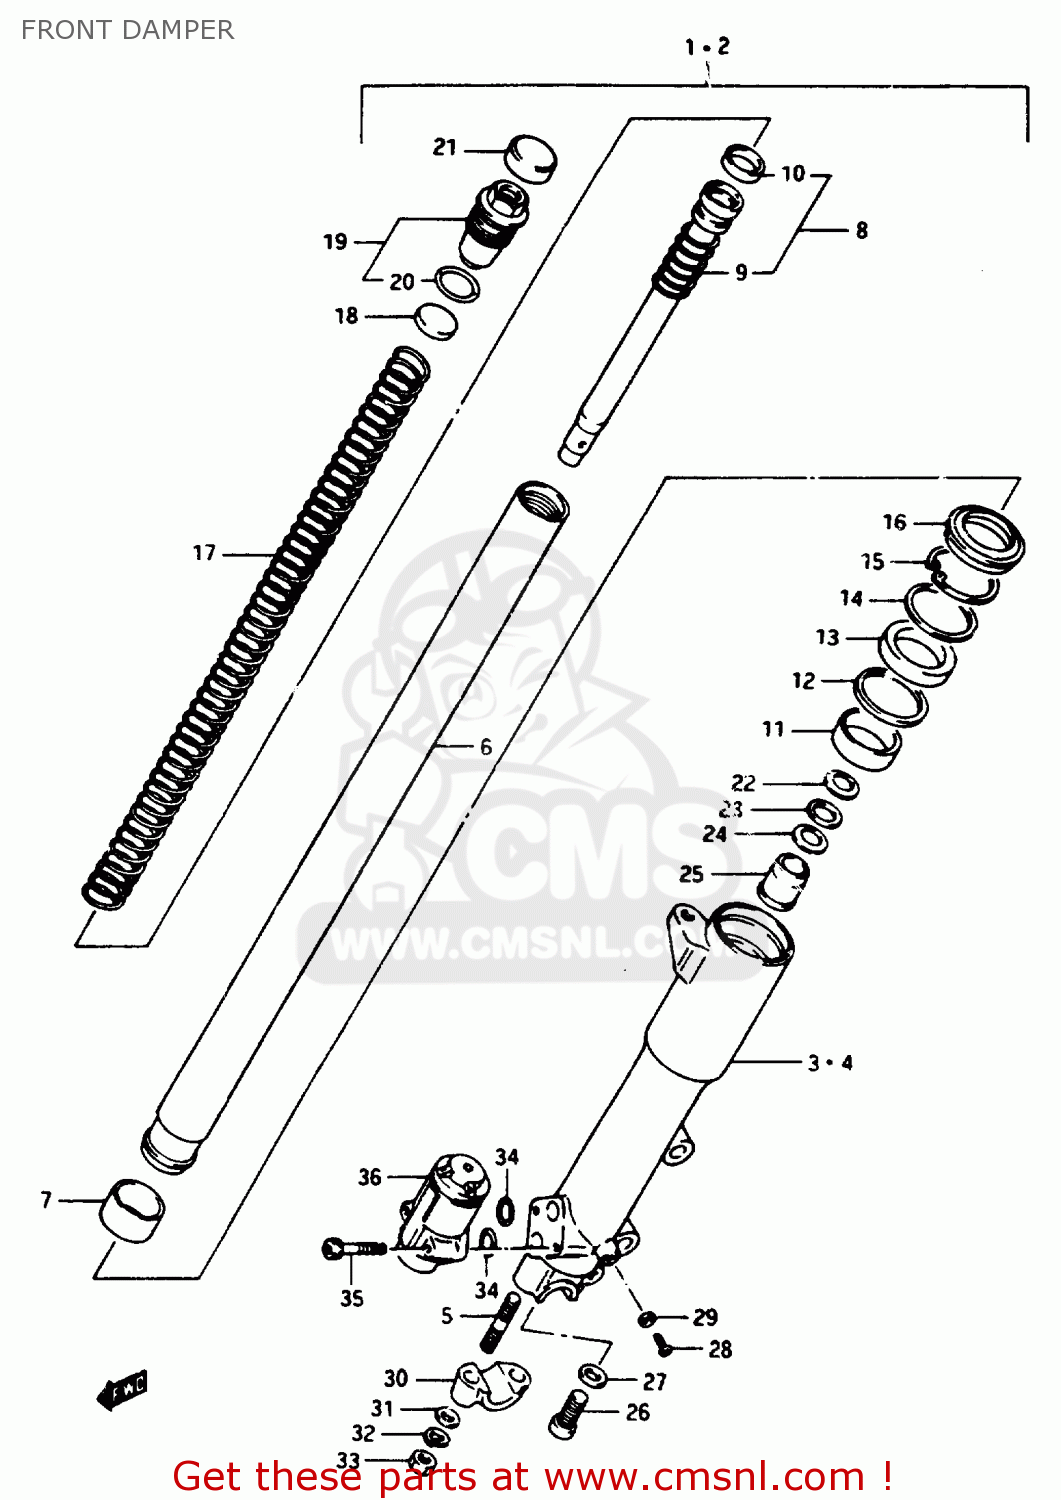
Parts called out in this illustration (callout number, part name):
1	DAMPER ASSY, RH
2	DAMPER ASSY, LH
3	TUBE,FORK,OUTER,RIGHT
4	TUBE,FORK,LEFT,OUTER
5	STUD 8X30
6	TUBE, INNER
7	METAL,FR FORK PISTON
8	CYLINDER,FRONT FORK
9	SPRING,FORK REBOUND
10	RING,FR FORK PISTON
11	METAL,SLIDE
12	WASHER
13	SEAL,OIL
14	WASHER,FORK OIL SEAL
15	RING,STOPPER
16	SEAL,DUST
17	SPRING
18	WASHER
19	CAP
20	O RING
21	CAP,FORK INNER TUBE
22	SPRING,LEAF
23	WASHER
24	SPRING,LEAF
25	PIECE,OIL LOCK
26	BOLT,FORK CYLINDER(10X25)
27	GASKET (NAS)
28	SCREW
29	GASKET,DRAIN,PLUG (NAS)
30	HOLDER,AXLE
31	WASHER
32	WASHER,LOCK,8.
33	NUT
34	O RING
35	BOLT
36	P.D.F ASSY
